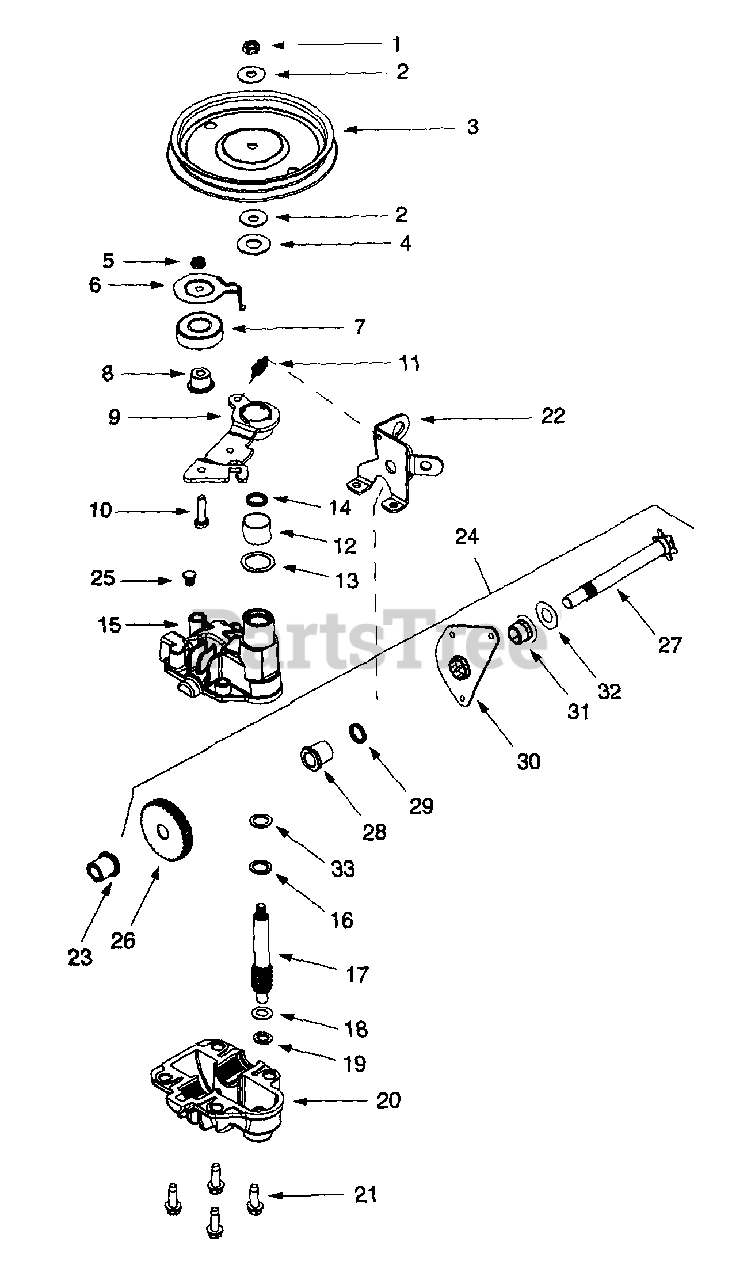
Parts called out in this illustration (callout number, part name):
1	Hx. Jam Nut, 5/16-24
2	Bell Wash. .325 x .930 x .045
3	Pulley
4	Fl. Wash. .510 x 1.120 x .060
5	Hx, Jam Nut, 1/4-28
6	Belt Keeper
7	Bearing
8	Flange Spacer
9	Idler Bracket Assembly
10	Hx. Cap Scr. 1/4-28 x 1.00 Gr. 5
11	Extension Spring
12	Bearing Sleeve
13	Fl. Wash. .885 x 1.145 x .030
14	Oil Seal
15	Upper Housing Assembly
16	Thrust Wash. .504 x .700 x .030
17	Pinion Shaft, 10T.
18	Thr. Wash. 3/8 x .70 x .030
19	Thr. Wash. .388 x .625 x .062
20	Lower Housing Assembly
21	Hx. Scr. 1/2-20 x .75
24	Shaft Assembly
26	Gear 34T.
27	Output Shaft, 6T.
28	Flange Bearing
29	Oil Seal
30	Pivot Bracket
31	Flange Bearing
32	Flat Washer
33	Bearing
